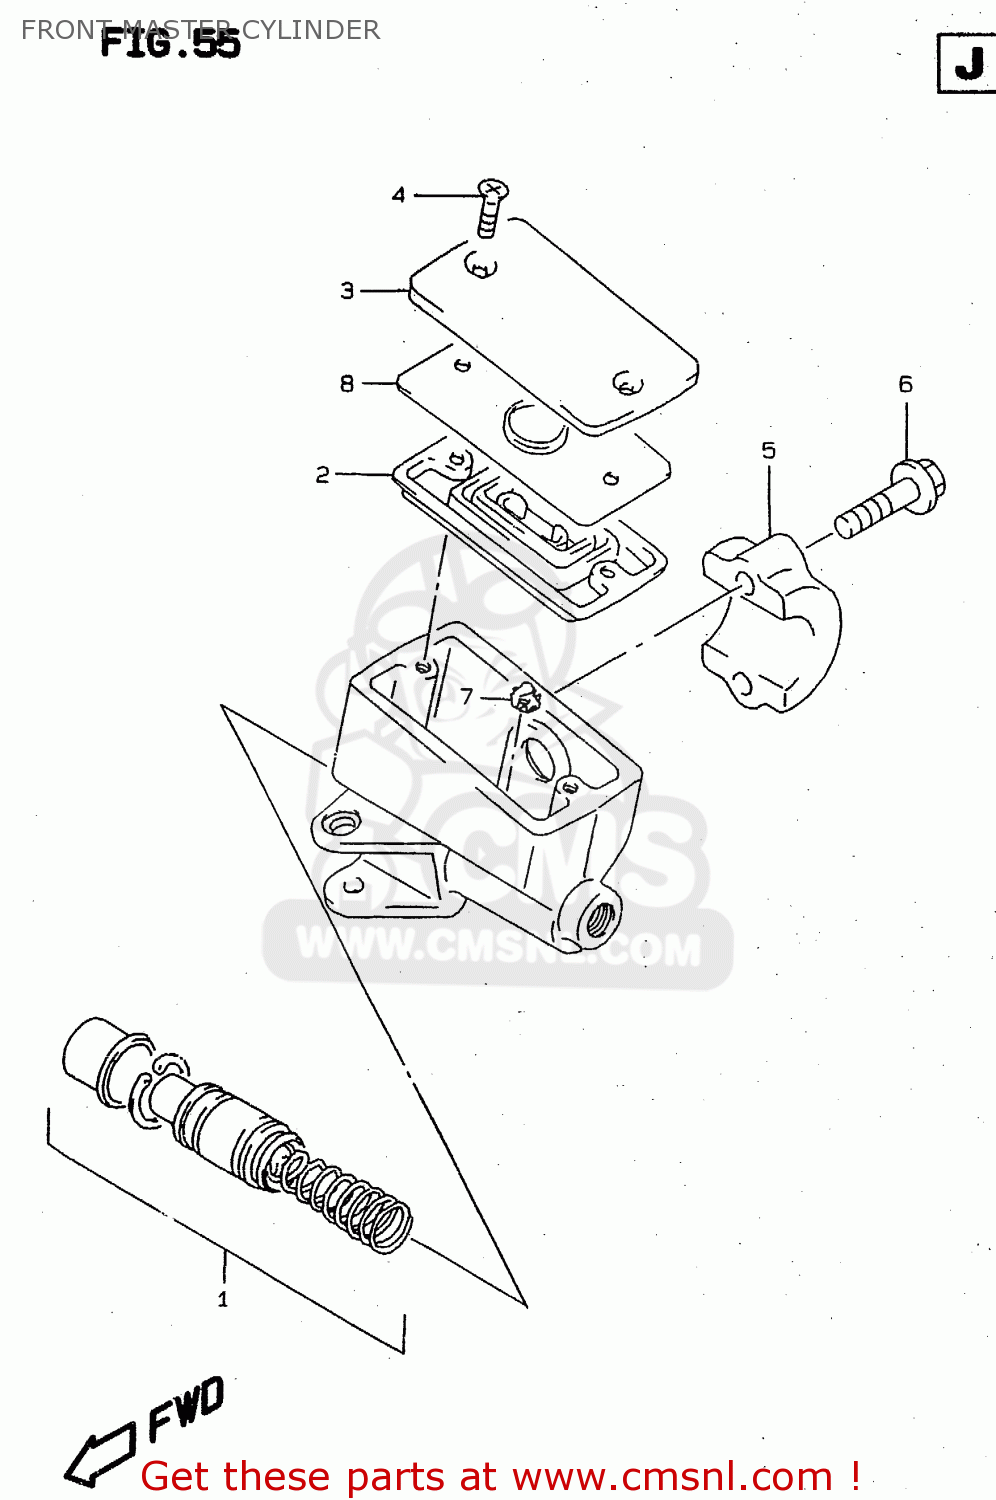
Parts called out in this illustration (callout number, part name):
1	PISTON & CUP SET
2	3
3	CAP
4	SCREW
5	HOLDER
6	BOLT(6X25)
7	PROTECTOR
8	PLATE,DIAPHRAGM
